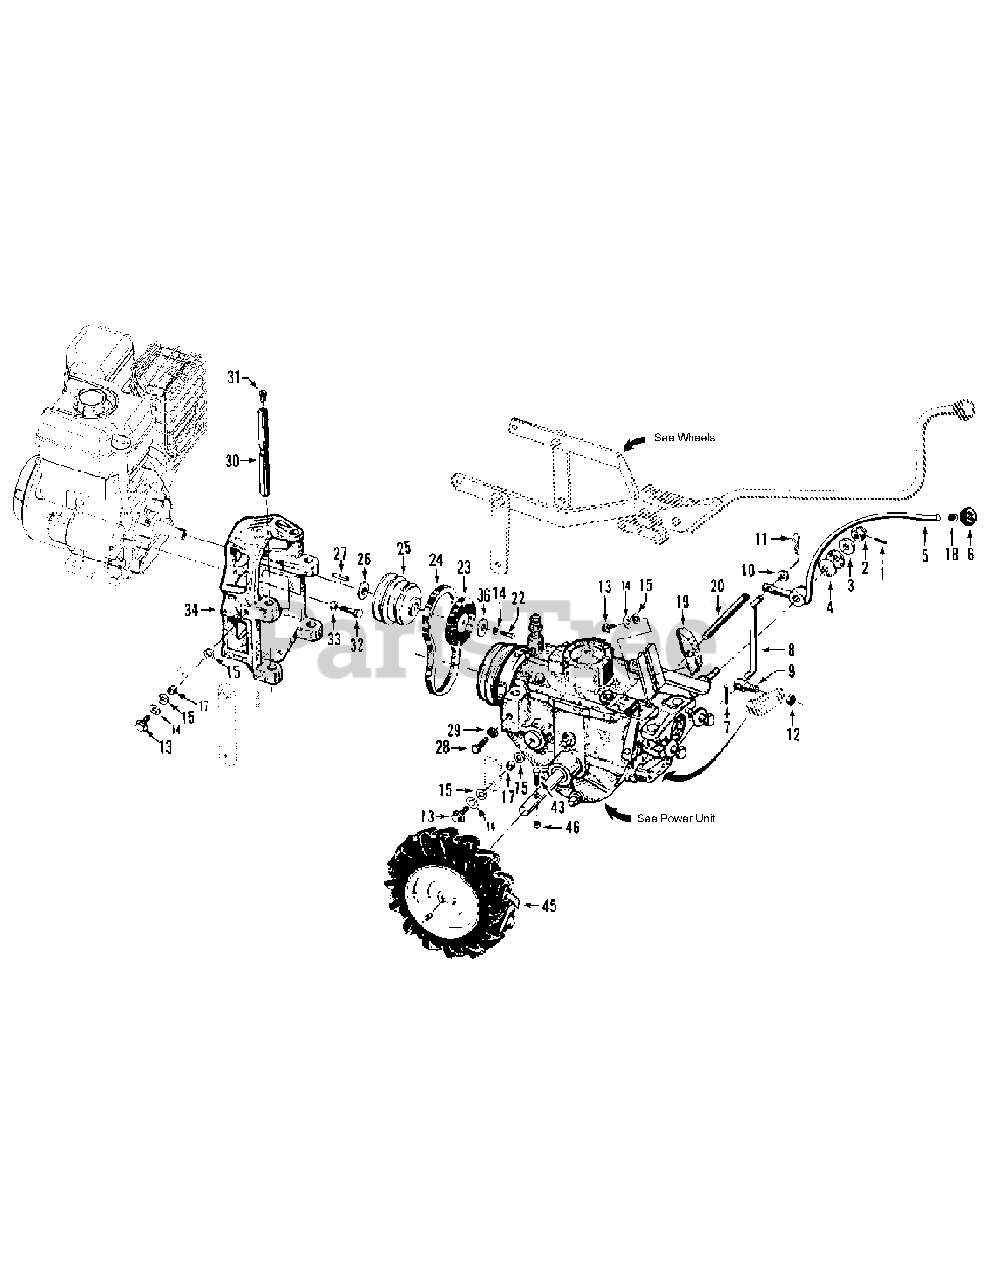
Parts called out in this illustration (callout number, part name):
1	Pin-spring, 1/8"
2	Nut-castle (slotted), 1/2"-20
3	Washer-shoulder, 1/2"
4	Washer-disc spring
5	Lever-wheel speed shift
6	Knob-wheel speed shift lever
7	Pin-cotter, 3/32" x 1"
8	Connecting rod, wheel speed -shift lever (incl. Refs. 7 & 9)
9	Swivel-connecting rod
10	Washer-flat, 5/16", SAE
11	Pin-hair cotter
12	Locknut-hex hd., 5/16"-18
13	Bolt-flanged hex hd., 3/8-16 x 1"
14	Lockwasher-spring lock, 3/8"
15	Washer-flat, 3/8", SAE
17	Bushing-spacer, 19/64" (.300" lg)
18	Ring-retaining (tolerance ring)
19	Block- belt adjustment, 3-7/8"
20	Rod- belt adjust., 7" with measuring gauge
21	Decal- engine stabilization
22	Bolt-hex hd., 3/8-24 x 1-1/2"
23	Disc-reverse
24	Belt-forward drive (no substitute due to extra strength required)
25	Pulley-engine power take off
26	Shim-engine pulley, 1/16"
26	Shim-as above, 1/32"
27	Key-engine pulley, 3/16"sq. x 2-1/2"
28	Bolt-hex hd., 5/16-18 x 1"; Grade 5
29	Nut, hex, 5/16-18
30	Bar-engine mounting
31	Plug-thread protector, red plastic
32	Bolt-hex hd., 5/16-24 x 1-1/8"
33	Lockwasher-spring lock, 5/16"
34	Mount- engine to tiller
36	Washer, flat, .406 x 1.0 x .105
36	Decal-hot surface warning
43	Screw, Hex, 1/4-20 x 1-1/2"
45	Wheel & Tire Ass'y. 16 x 4:6 x 8" tubeless tire with valve stem, on one-piece steel rim
46	Nut, Hex Flange, 1/4-20
